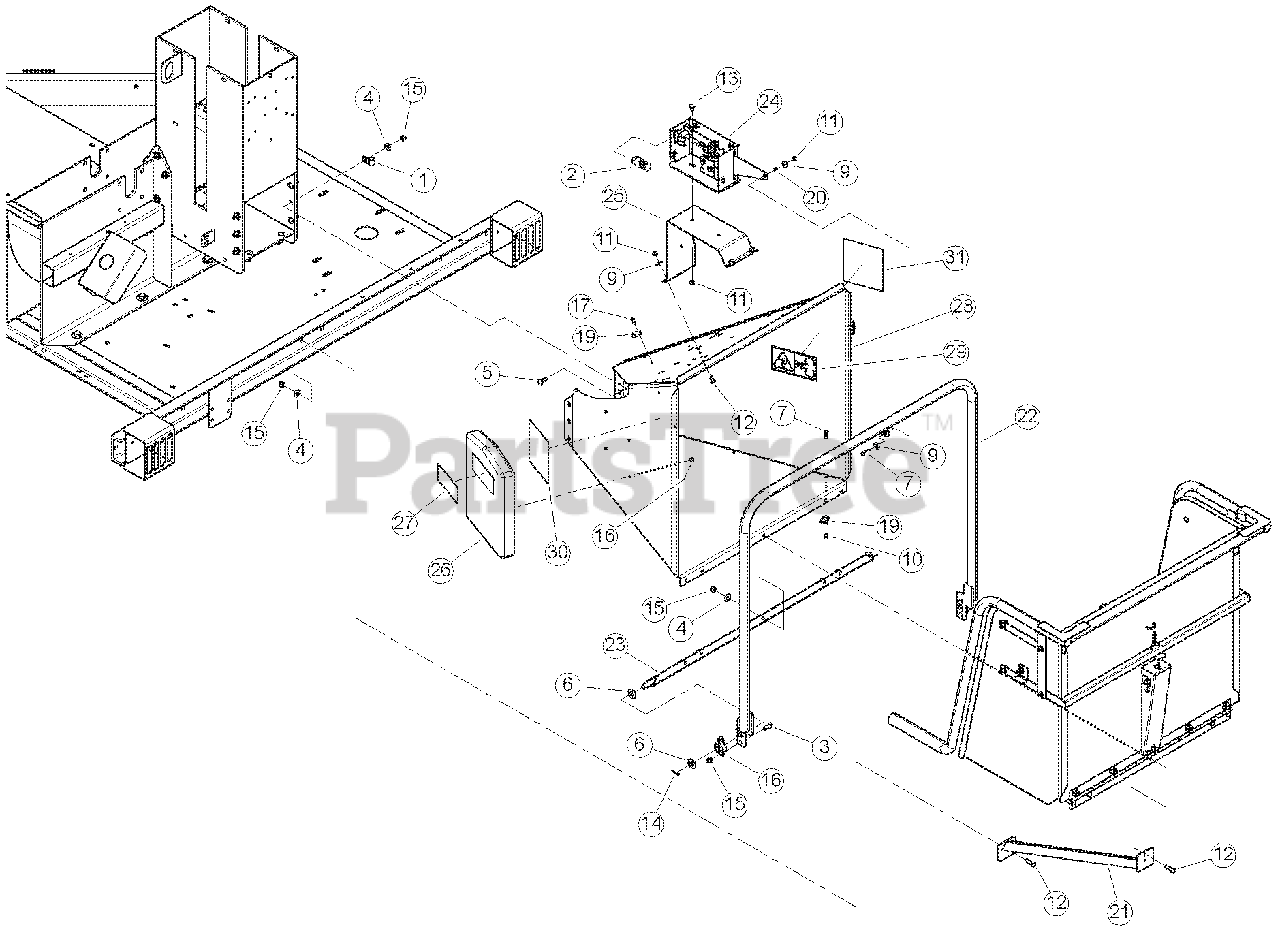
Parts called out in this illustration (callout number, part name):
1	CLAMP, 9/16" COATED
3	BOLT, 3/8 X 1 HEX HD GR5 ZP
4	WASHER, 3/8 FLAT ZP
5	BOLT, 3/8 X 1-1/2 CRG GR5 NC ZP
6	WASHER, 5/8 SAE FLAT ZP
7	BOLT, 5/16 X 1 HHCS GR5 NC ZP
8	BOLT, 1/4 X 1 CRG GR5 NC ZP
9	WASHER, 5/16 FLAT ZP
10	NUT, 1/4 NE NYLOCK ZP
11	NUT, 5/16 NE NYLOCK ZP
12	BOLT, 3/8 X 1-1/4 HEX HD GR5 ZP
13	BOLT, 5/16 X 3/4 CRG GR5 NC ZP
14	PIN, 1/8 X 1.00 ZP COTTER
15	NUT, 3/8 NE NYLOCK ZP
16	RIVET, AL BLIND 1/4 X 1/2 DOME HEAD
17	RIVET, AL BLIND 1/4 X 3/4 DOME HEAD
18	BEARING, SIDE FLANGE MOUNT, 5/8
19	CLAMP, CABLE MOUNT
20	SPACER, IDLER PIVOT
21	WELDMENT, CHUTE SUPPORT
22	WELDMENT, CONTROL ARM
23	WELDMENT, CONTROL PIVOT
24	ASSEMBLY, SWITCH BOX
25	MOUNT, SWITCH BOX
26	ASSEMBLY, MANUAL CONTAINER, SERVICE PART
27	DECAL, MUTILINGUAL MANUAL
28	ASSEMBLY, BIG CHIPPER CHUTE, SERVICE PART
29	DECAL, BLADE DANGER ISO
30	DECAL, FEED POSITION
31	DECAL, FEED POSITION
